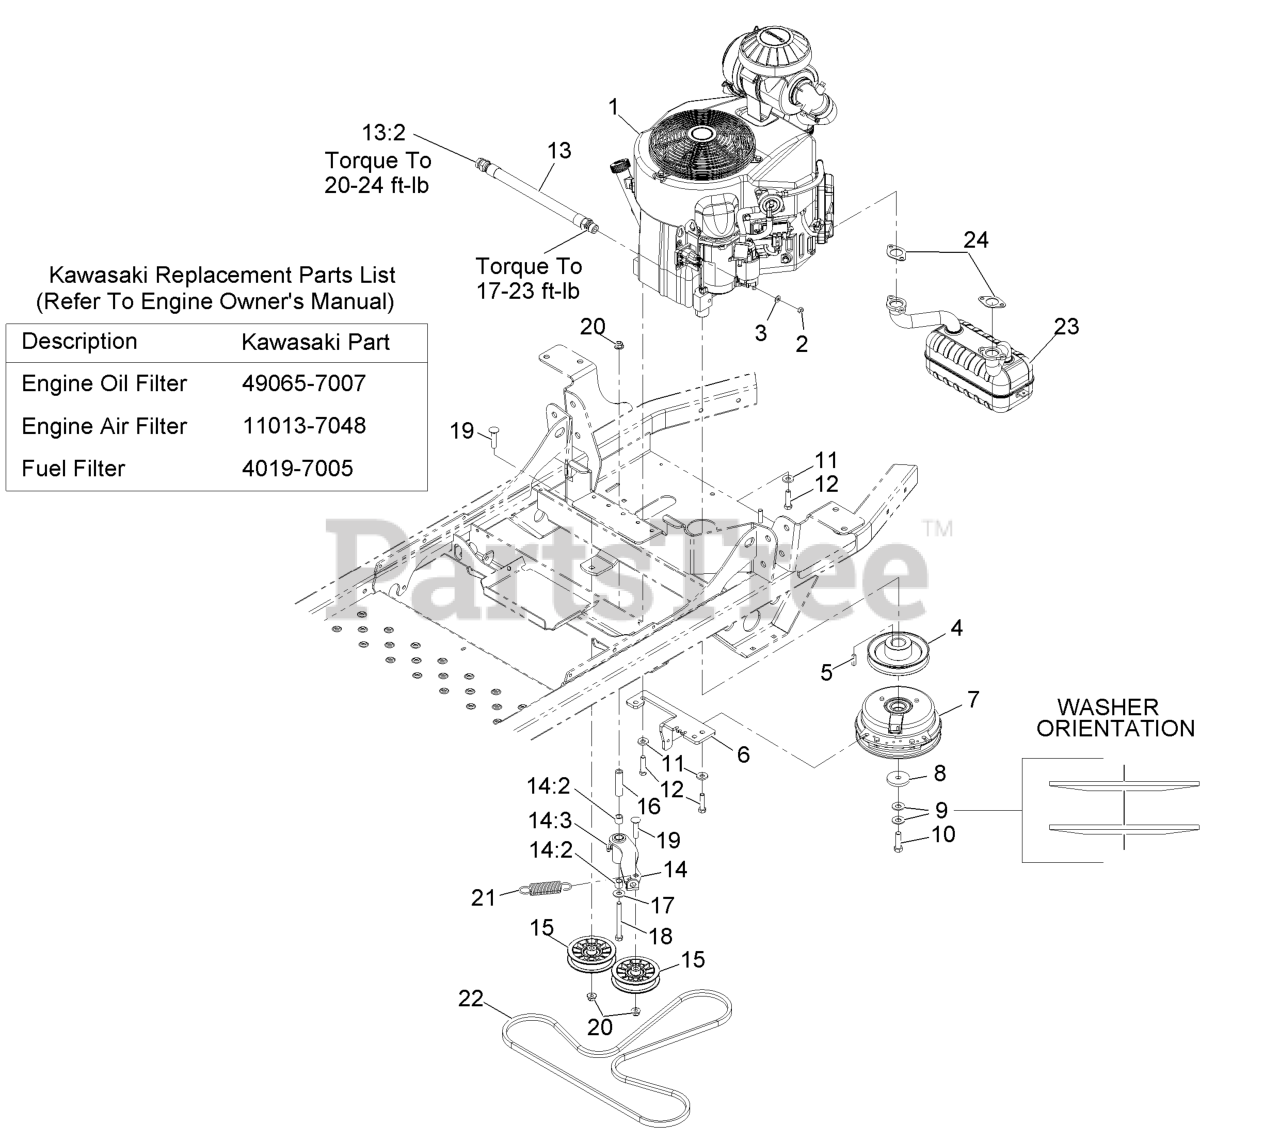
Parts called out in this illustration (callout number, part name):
2	NUT-HEX
3	WASHER-FLAT
4	SHEAVE-PUMP, DRIVE
6	ANCHOR-CLUTCH
8	WASHER-CLUTCH
9	WASHER-SPRING
10	SCREW-HH 7/16-20 X 1 1/2 W/LOCTITE
11	WASHER-BELLEVILLE
12	SCREW-HH
14:2	SLEEVE-BEARING
14:3	FITTING-GREASE, 90 DEG
15	PULLEY-FLAT IDLER
16	BUSHING-PIVOT, IDLER
17	WASHER-FLAT
18	SCREW-CARR
19	SCREW-CARR
20	NUT-HF, NI
21	SPRING-EXTENSION
22	V-BELT
23	MUFFLER-KAWASAKI
24	GASKET-EXHAUST
